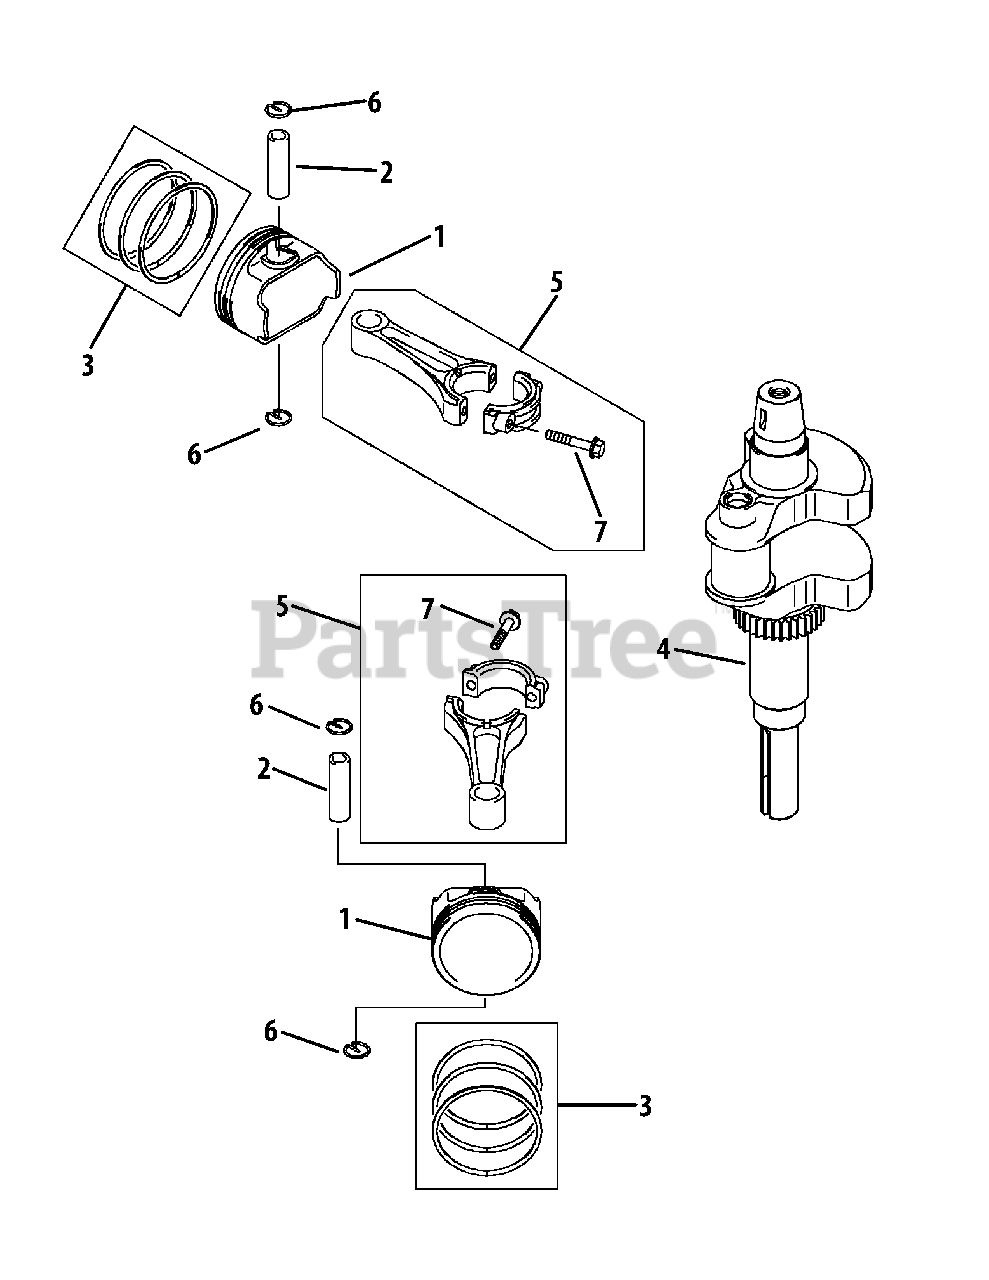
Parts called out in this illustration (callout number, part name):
1	Engine Piston
1	Engine Piston, L 0.50
3	Piston Ring Set
3	Piston Ring Set, L 0.50
5	Connecting Rod
6	Snap Ring
7	Bolt, 6 x 35
